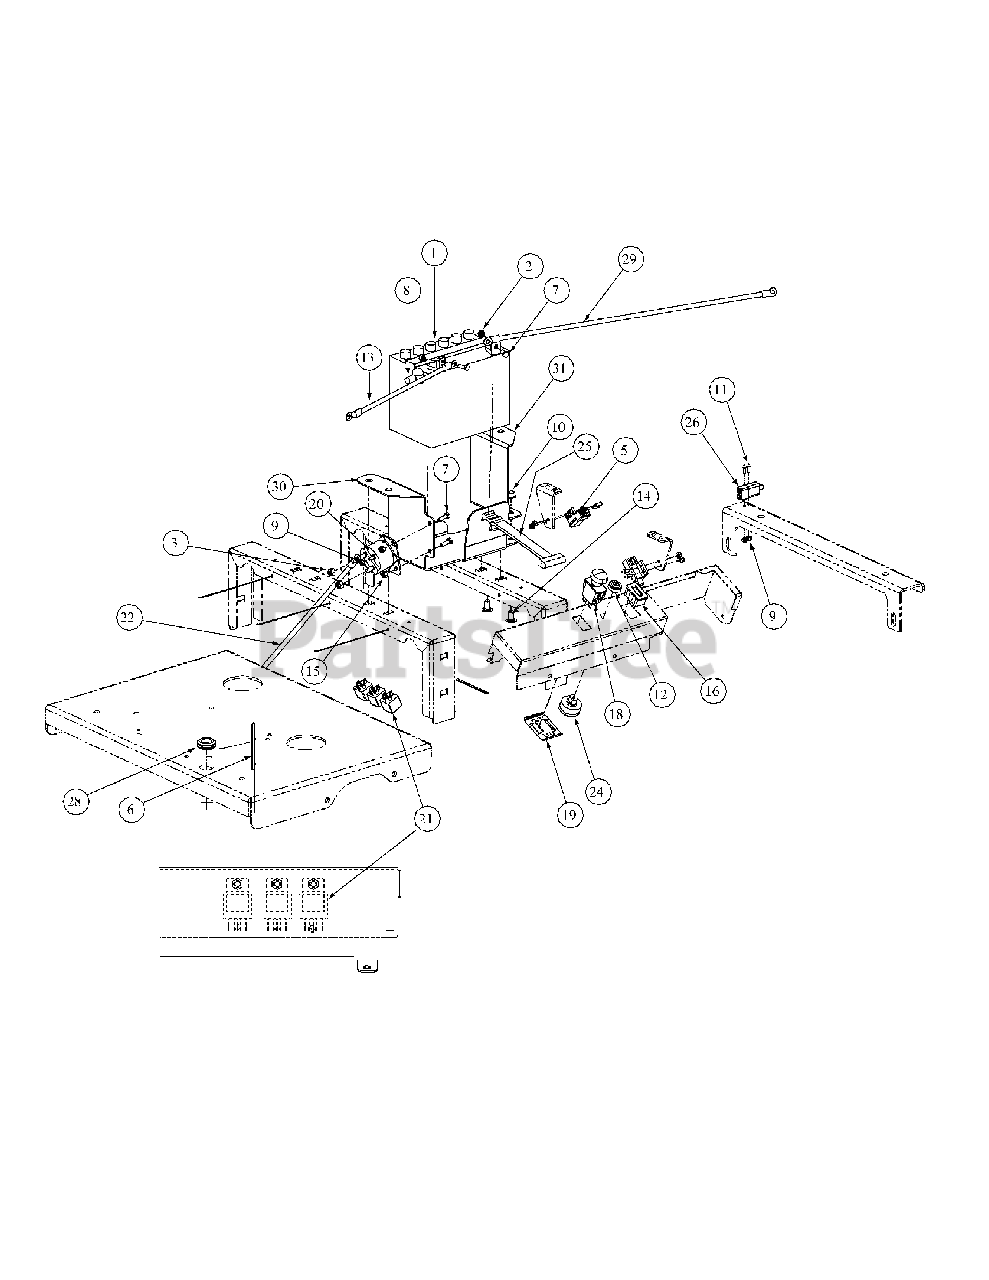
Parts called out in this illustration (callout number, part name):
1	Battery, 12V 225CCA 30 Min
2	Hex Flange Lock Nut, 1/4-20
3	Nylock Nut, 5/16-18
5	Switch, Safety
6	Tie, Cable, 3/16 x .05 x 7.4"
7	Screw, Hex, Cap, 1/4-20 x .75
8	Boot, 1" OD Rubber Battery-PST, Red
9	Nut, Lock, Nylon Insert, #10-32
10	Nut, Hex, Flange Lock, 3/8-16
11	Screw, Phillips Head, Machine, 10-32 x 5/8
12	Nut, W/Cap, 5/8-32 Ignition
13	Cable, Battery, Red, 15"
14	Carriage Bolt, 3/8-16 x .75 LG.
15	Lock Nut w/Nylon Insert
16	Meter, Hour
18	Switch, Electric, PTO
19	Bracket, PTO Switch Retainer
20	Solenoid Magnetic Switch
21	Relay, 12V 40A
22	Cable, Battery Red, 32"
24	Switch, Ignition, 6 Pin
24	Key, Ignition
25	Strap, Battery
26	Switch, Plunger
28	Grommet, .75 ID
29	Cable, Battery Black, 28"
30	Mount Bracket, Battery
31	Mount Bracket, Battery
